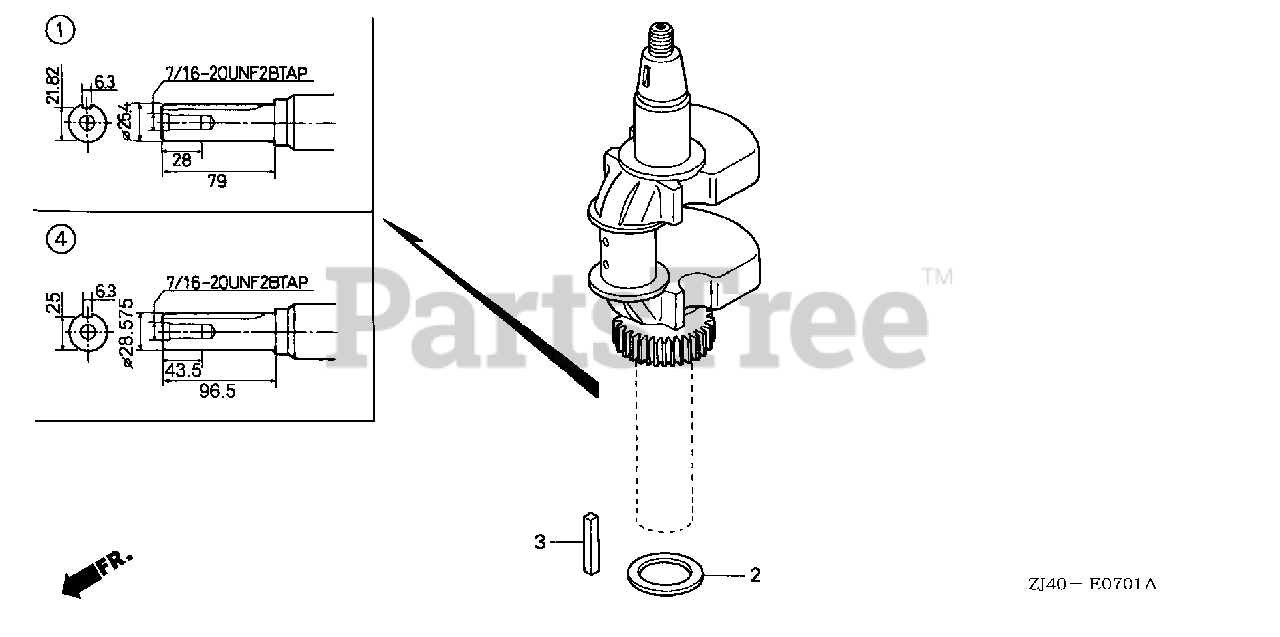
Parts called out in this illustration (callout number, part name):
2	WASHER, CRANKSHAFT THRUST (38.5X54.0X1.0)
3	KEY (6.3X6.3X43)
4	CRANKSHAFT
